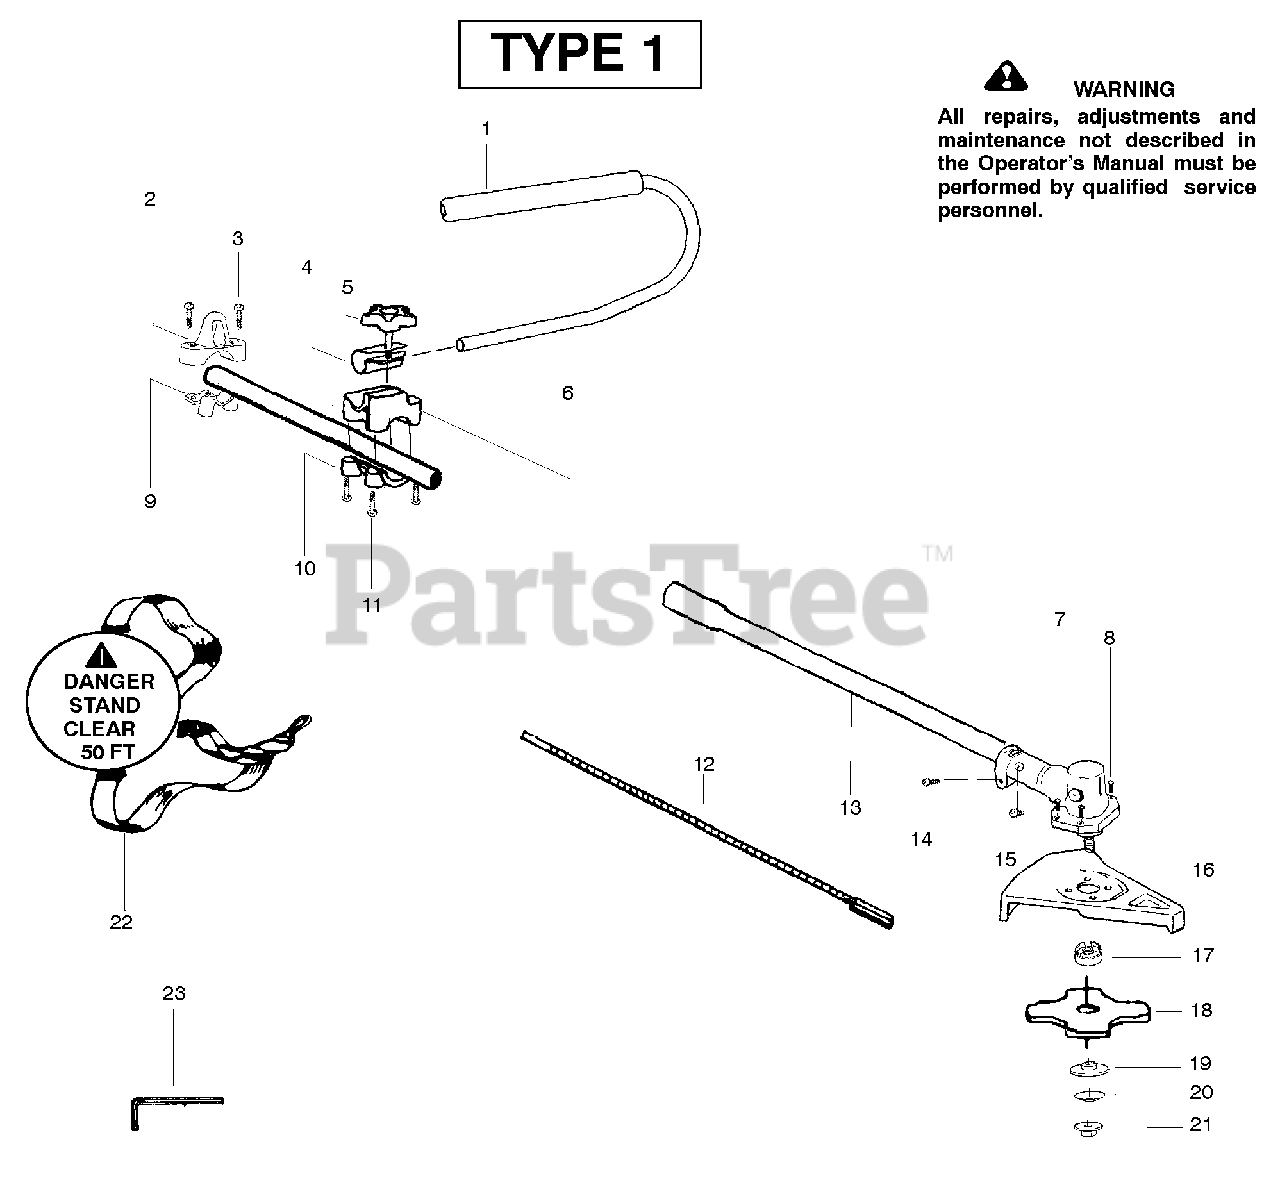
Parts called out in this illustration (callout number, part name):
1	Kit-Handlebar
2	Clamp-Harness Upper
3	Screw
4	Clamp-Handlebar
5	Knob
6	Base-Clamp
9	Clamp-Harness Lower
10	Kit-Clamp-Tube
11	Screw
12	Flexshaft-Split boom
13	Assy.-Driveshaft
15	Screw-Alignment
16	Kit-Blade Shield
17	Dust cup - Blade
18	Accy.-Weed Blade (8")
19	Washer-Blade Retaining
20	Washer-Belleville
22	Assy-Shoulder Strap
23	Wrench-Hex (5/32")
